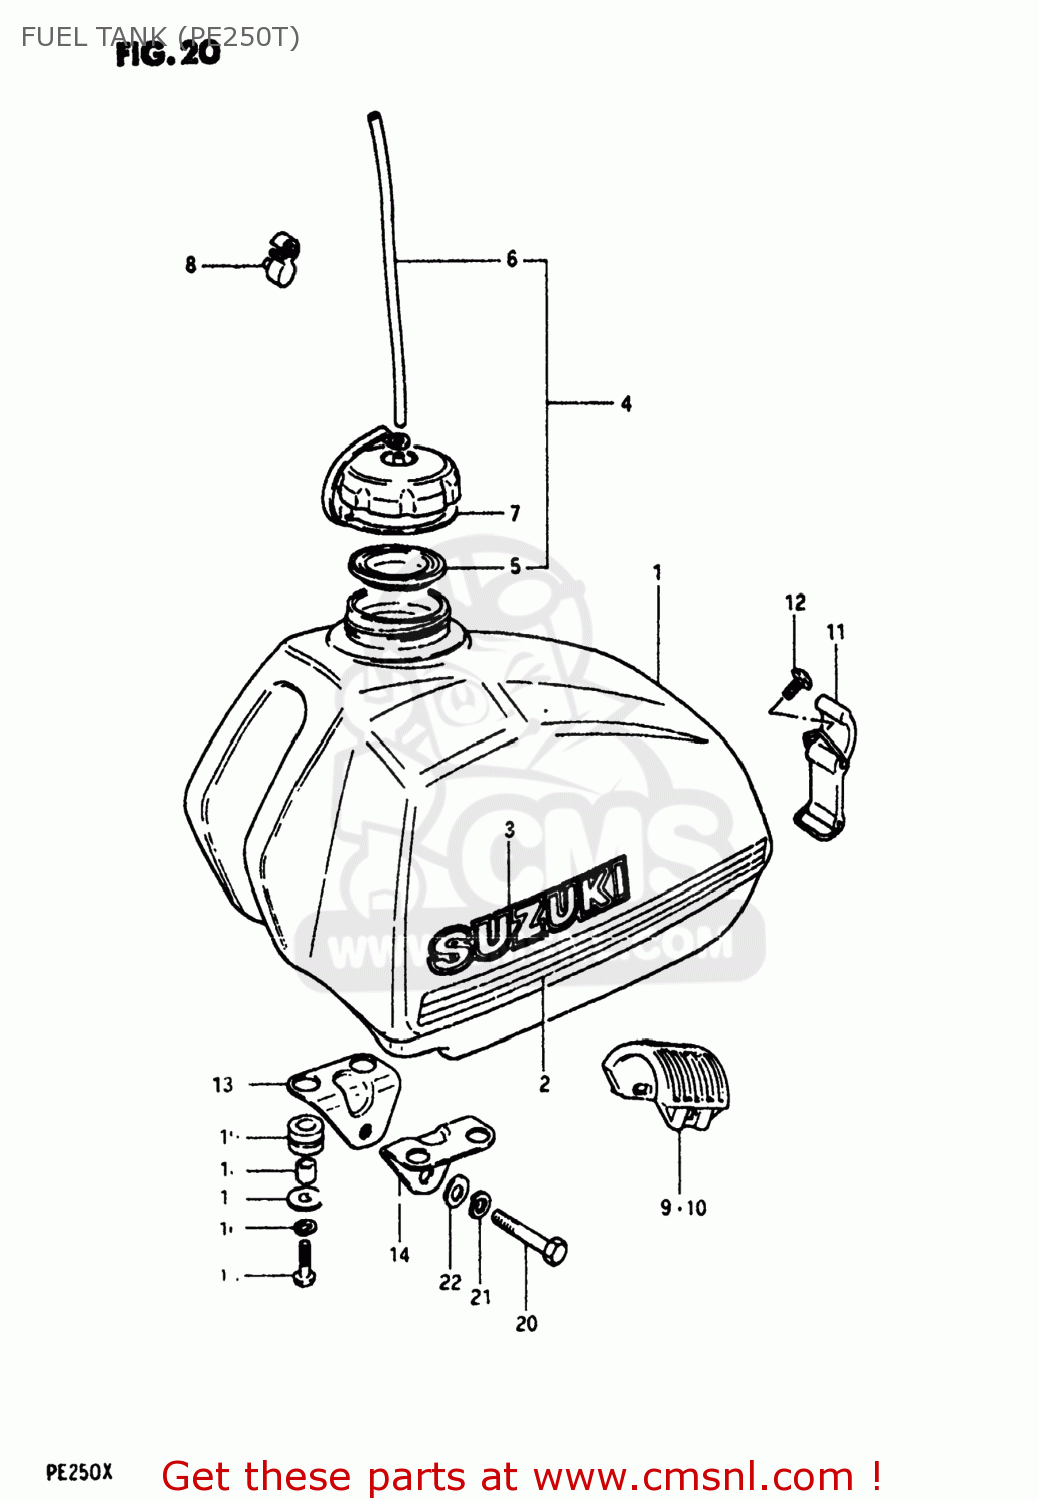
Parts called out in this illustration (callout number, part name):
1	TANK ASSEMBLY,FUEL
2	TAPE SET,FUEL TANK
3	EMBLEM
4	CAP,FUEL TANK
5	GASKET,FUEL TANK CAP (NAS)
6	HOSE
7	BAND,FUEL TANK CAP
8	CLAMP,BREATHER HOSE
9	CUSHION,FUEL TANK
10	CUSHION,FUEL TANK
11	BAND
12	SCREW(6X18)
13	BRACKET,FUEL TANK
14	BRACKET,FUEL TANK,LOWER
15	SCREW
16	LOCK WASHER
17	WASHER (6.5X24X1.6)
18	SPACER(6.8X12X11)
19	CUSHION
20	BOLT
21	LOCK WASHER
22	WASHER
